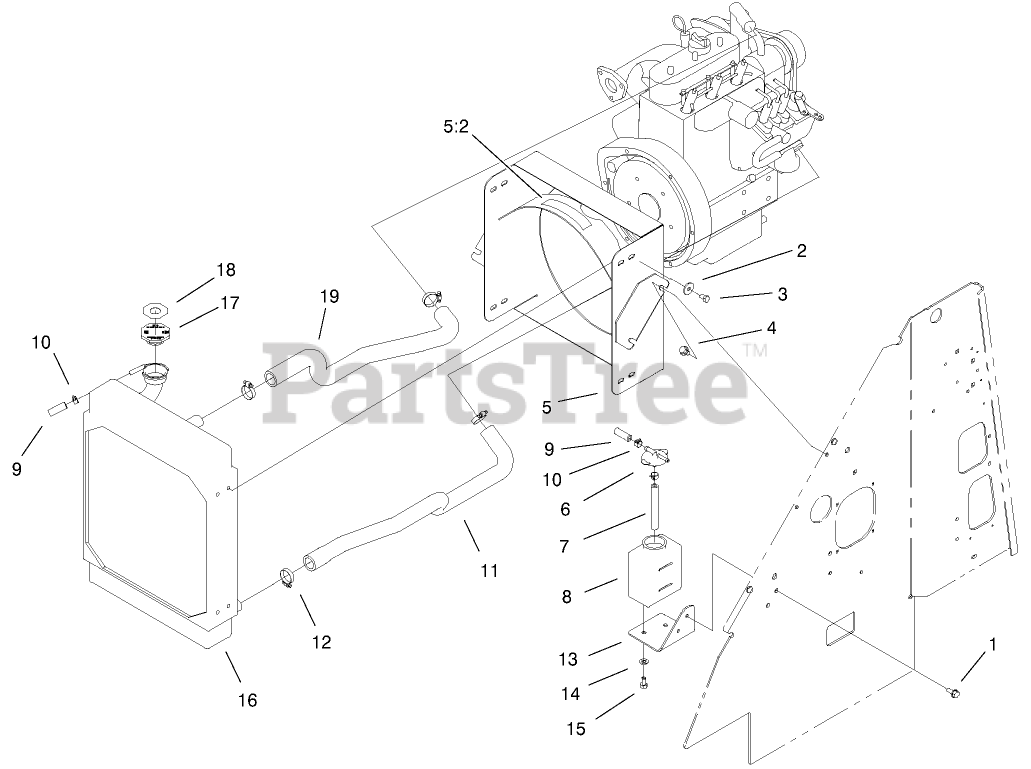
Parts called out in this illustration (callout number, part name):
1	SCREW-HWHTF
2	WASHER-FLAT
3	SCREW-HH
4	SCREW-HWHTF
5	ShroudASM
5:2	DECAL-WARNING, FAN
6	CAP-TANK, OVERFLOW
7	HOSE-FUEL
8	TANK-OVERFLOW
9	HOSE-FUEL
10	CLAMP-HOSE
11	HOSE-RADIATOR, LOWER
12	CLAMP-HOSE
13	MOUNT-TANK, OVERFLOW
14	WASHER-PLAIN
15	BOLT
16	RADIATOR
17	CAP-RADIATOR
18	DECAL-CAP, RADIATOR
19	HOSE-RADIATOR, UPPER
